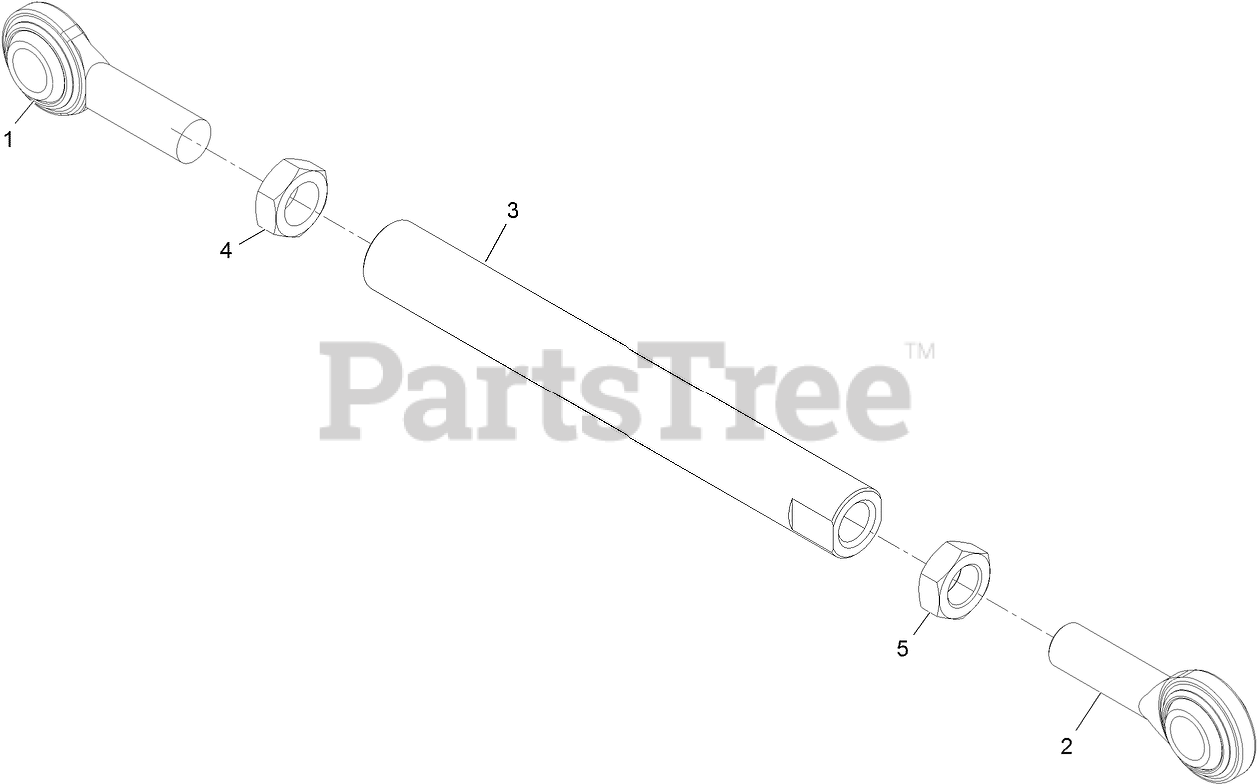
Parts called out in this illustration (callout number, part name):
1	BALLJOINT-SPHERICAL
2	BALLJOINT-SPHERICAL
3	ROD, LIFT
4	NUT-JAM
5	NUT-JAM
